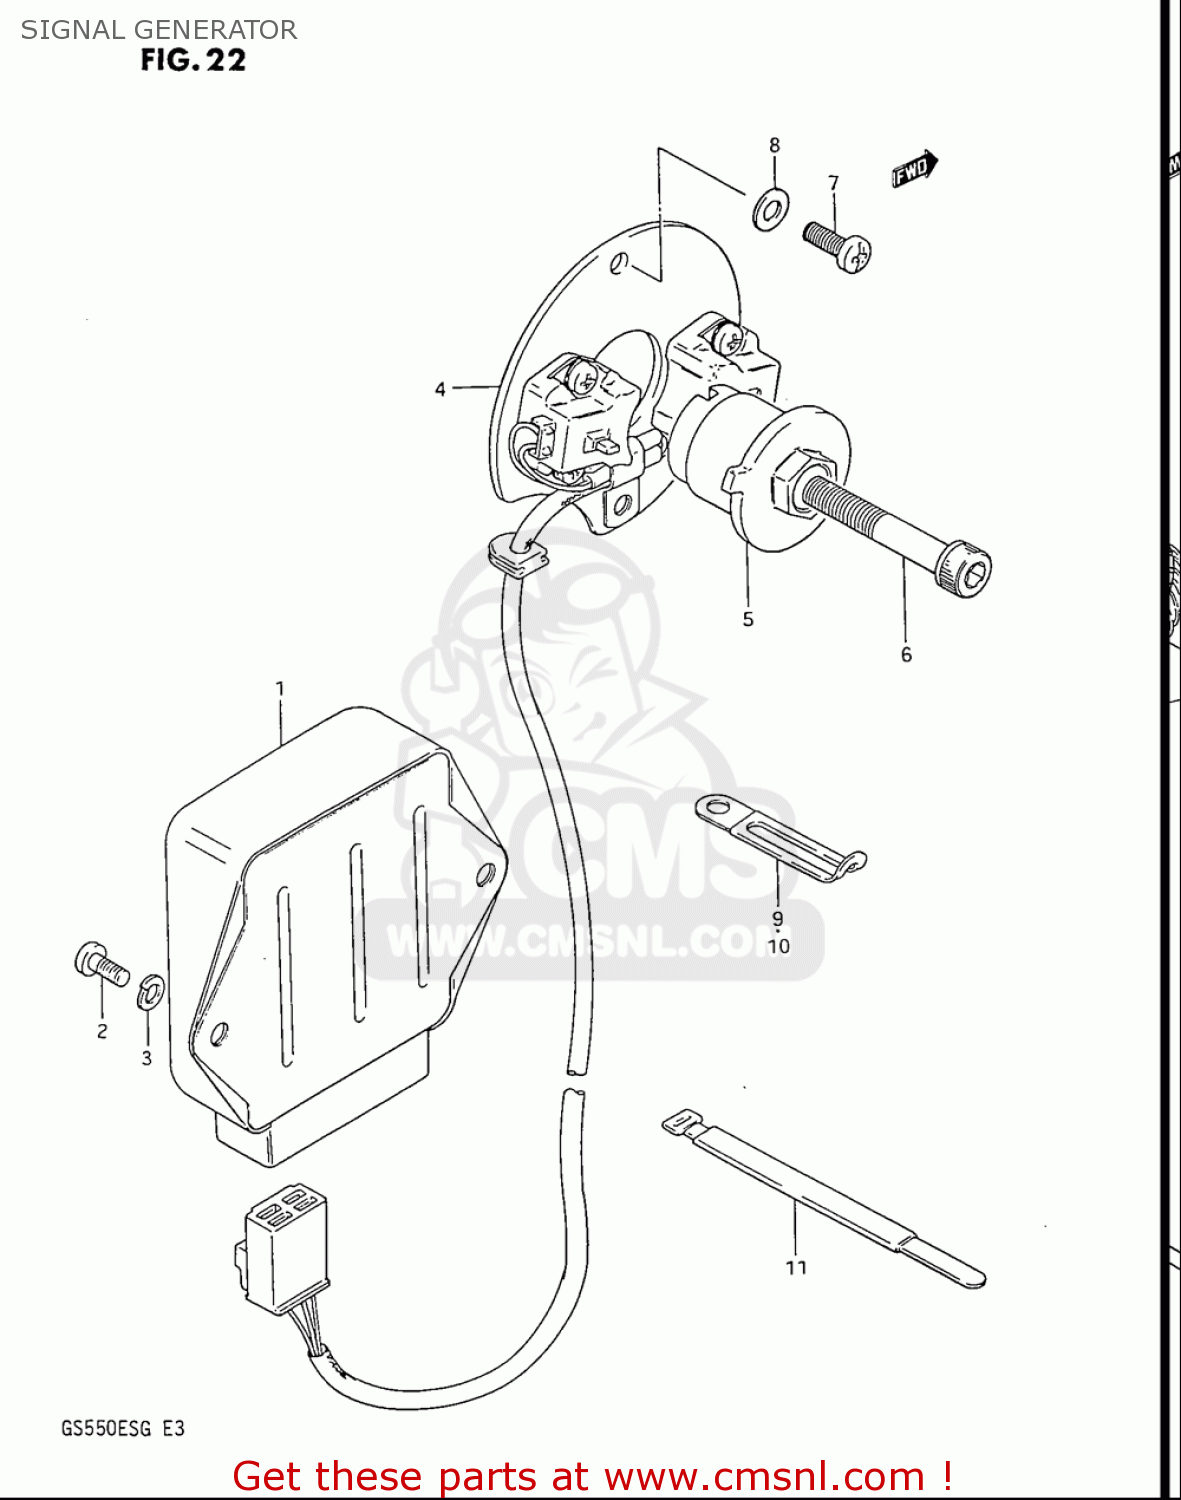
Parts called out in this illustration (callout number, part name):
1	IGNITOR UNIT ASSY
2	SCREW
3	WASHER,LOCK
4	GENERATOR ASSY,SIGNAL
5	ROTOR,SIGNAL
6	BOLT
7	SCREW(5X12)
8	WASHER
9	CLAMP(L:65)
10	CLAMP(L:120 T:1.0)
11	CLAMP
